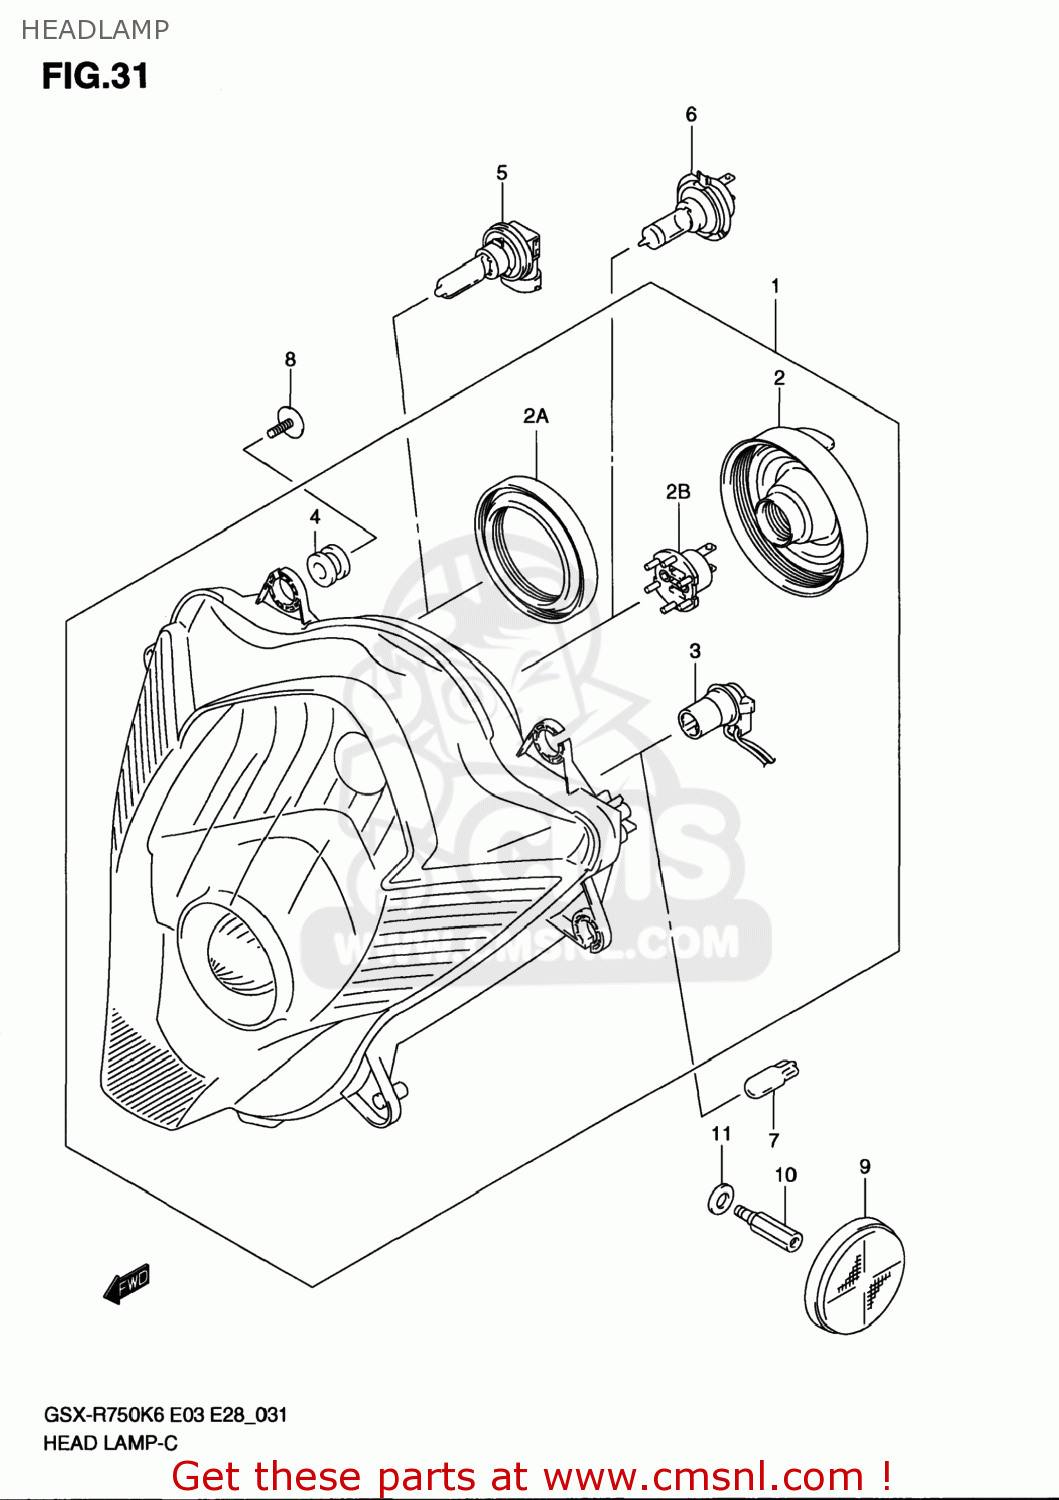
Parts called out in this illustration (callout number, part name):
1	HEADLAMP ASSY
2	COVER,SOCKET
2A	COVER,SOCKET
2B	ADAPTER ASSY
3	CORD ASSY
4	CUSHION
5	BULB(12V65W,H9)
6	BULB(12V55W/H7/PX26D/PHILIPS)
7	BULB(12V5W)
8	SCREW(5X15)
9	REFLECTOR,REFLEX FR
10	BOLT
11	WASHER (8.5X14X1.6)
